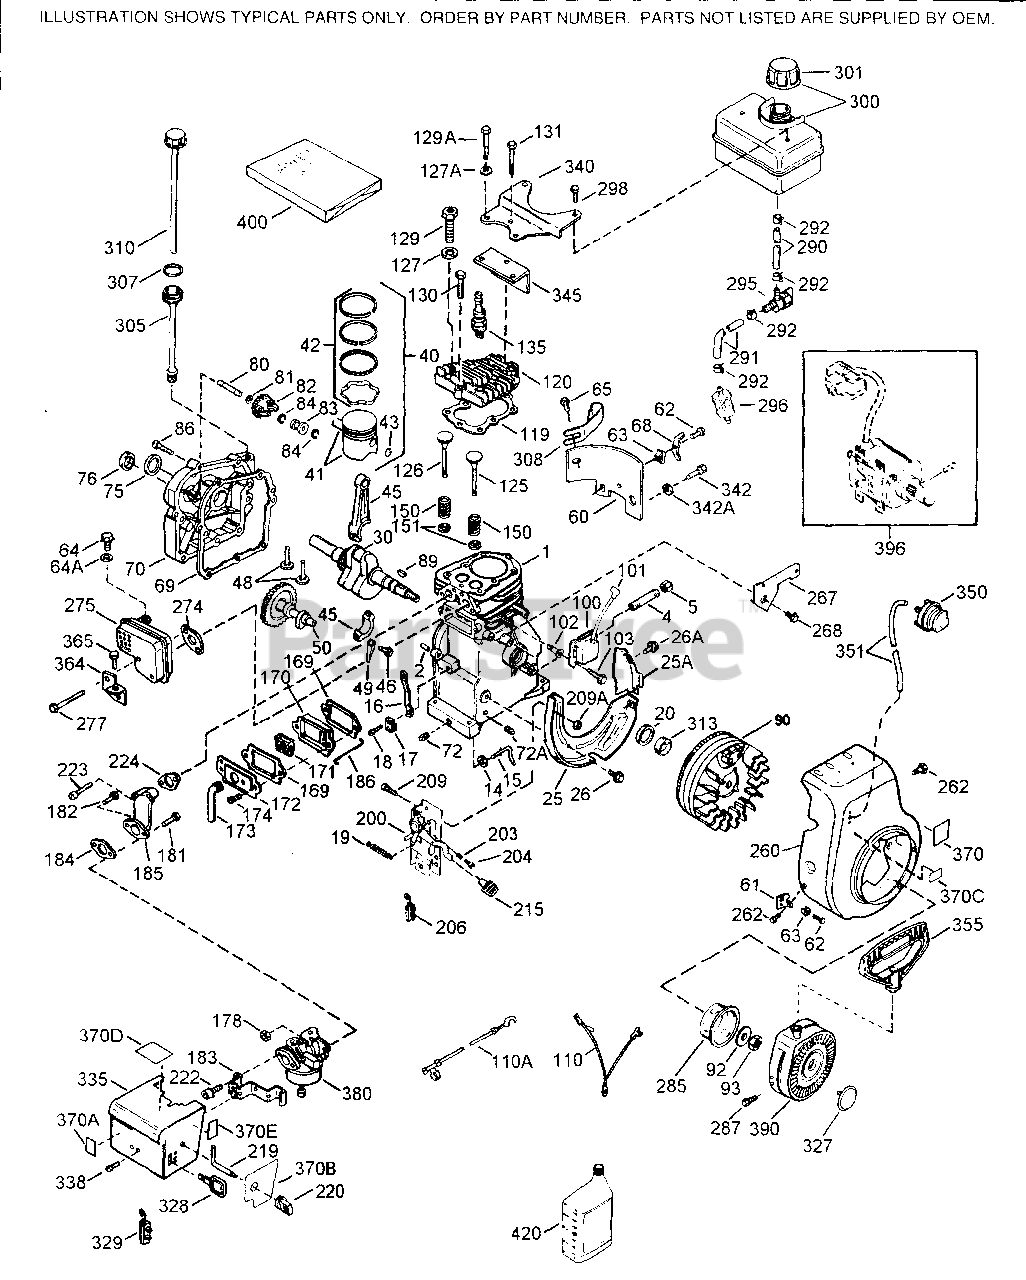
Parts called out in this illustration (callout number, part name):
1	"Cylinder (Incl. 2,20,72 & 125)
2	Dowel Pin
4	Oil Drain Extension
5	Extension Cap
14	Flat Washer
15	Governor Rod
16	Governor Lever
17	Governor Lever Clamp
18	Screw, 8-32 x 5/16"
19	Extension Spring
20	Oil Seal
25	Blower Housing Baffle
25A	Baffle Extension
28	Lock Nut, 8-32
30	Crankshaft
40	Piston, Pin & Ring Set (Std.) (Incl. 41, 42 & 43)
40	Piston, Pin & Ring Set (.010" OS) (In cl. 41, 42 & 43)
40	Piston, Pin & Ring Set (.020" OS) (In cl. 41, 42 & 43)
41	Piston & Pin Assembly (Std.) (Incl. 4 3)
41	Piston & Pin Assembly (.010" OS) (Inc l. 43)
41	Piston & Pin Assembly (.020" OS) (Inc l. 43)
42	Ring Set (Std.)
42	Ring Set (.010" OS)
42	Ring Set (.020" OS)
43	Piston Pin Retaining Ring
45	Connecting Rod Ass'y. (Incl. 46 & 49)
46	Connecting Rod Bolt
48	Valve Lifter
49	Oil Dipper
50	Camshaft (BCR)
60	Blower Housing Extension
61	Grommet Mounting Bracket
62	Screw, 8-32 x 3/8"
63	Breather Tube Grommet
64A	Washer
65	Screw, 10-24 x 9/16"
69	* Cylinder Cover Gasket
70	Cylinder Cover (Incl. 75 thru 83)
72	Oil Drain Plug (Sq. hd., 1/4-18)
75	Oil Seal
76	Camshaft Seal
80	Governor Shaft
82	Governor Gear Ass'y. (Incl. 81)
83	Governor Spool
86	Screw, 1/4-20 x 1-1/4"
89	Flywheel Key (also available in Packa ged Part #740007B)
90	Flywheel (W/Ring Gear)
92	Belleville Washer
93	Flywheel Nut
100	Solid State Ignition
101	Spark Plug Cover
102	Solid State Mounting Stud
103	Screw, Torx T-15, 10-24 x 15/16"
110	Ground Wire
110A	Ground Wire
119	* Cylinder Head Gasket
120	Cylinder Head (Incl. 131)
125	Exhaust Valve (Std.) (Incl. 151)
125	Exhaust Valve (1/32" OS) (Incl. 151)
126	Intake Valve (Std.) (Incl. 151)
126	Intake Valve (1/32" OS) (Incl. 151)
129	Screw, 5/16-18 x 1-1/2"
130	Screw, 5/16-18 x 1-1/2"
130B	Screw, 1/4-20 x 1/2"
131	Screw, 5/16-18 x 2"
135	Resistor Spark Plug - RJ17LM
150	Valve Spring
151	Valve Spring Cap
161	Screw, T-30, 1/4-20 x 1/2"
169	* Valve Cover Gasket
170	Breather Body
171	Breather Element
172	Valve Cover
173	Breather Tube
174	Screw, 10-24 x 1/2"
178	Nut & Lock Washer 1/4-28
181	Screw, 1/4-28 x 7/8"
182	Screw, 1/4-28 x 1-11/16"
183	Choke Bracket
184	* Carburetor To Intake Pipe Gasket
185	Intake Pipe
186	Governor Link
200	Control Bracket (Incl. 203 thru 209A)
203	Compression Spring
204	Screw, 5-40 x 7/16"
206	Terminal
209	Screw, 8-32 x 1/2"
215	Control Knob
219	Choke Rod
220	Control Knob
222	Screw, 10-32 x 1/2"
223A	Screw, 1/4-20 x 1-19/32"
224	* Intake Pipe Gasket
260	Blower Housing
264A	Screw, 1/4-20 x 5/8"
267	Hold Down Bracket
274	* Exhaust Gasket
275	Muffler (Incl. 274)
277	Screw, 1/4-20 x 2-1/2"
285	Starter Cup
287	Screw, 8-32 x 21/64"
290	Fuel Line (12.62")
292	Fuel Line Clamp
298	Screw, 1/4-15 x 7/8"
300	Fuel Tank (Incl. 292 & 301) (2 Quart)
301	Fuel Cap (Red)
305	Oil Fill Tube
307	"O" Ring
308	Fill Tube Clip
310	Dipstick
319	Screw, 10-24 x 3/8"
327	Starter Plug
328	Ignition Key
335	Carburetor Cover
338	Screw, 8-32 x 5/16"
340	Fuel Tank Bracket
345	Heat Baffle
350	Primer Ass'y.
351	Primer Line
355	Starter Handle (Mitten Grip) also ava ilable in Packaged Part #740053B
364	Carburetor Cover Bracket
370	Decal - Speed Control & Choke
370	Decal - Primer - International Symbol
370D	Warning Decal
380	Carburetor (Incl. 184)
390	Rewind Starter NOTE: This engine cou ld have been built with 590646 starte r. Refer to the design of the air int ake louvers for part identification. Individual starter parts do not inter change.
396	Electric Starter Motor (110 Volt) Opt ional
400	* Gasket Set (Incl. items marked PK in notes) Incl. part #'s 26756 (1), 2723 4A (2), 27272A (1), 27677A (1), 29673 (1), 36440 (1), 32649A (1), 33670A ( 1)
